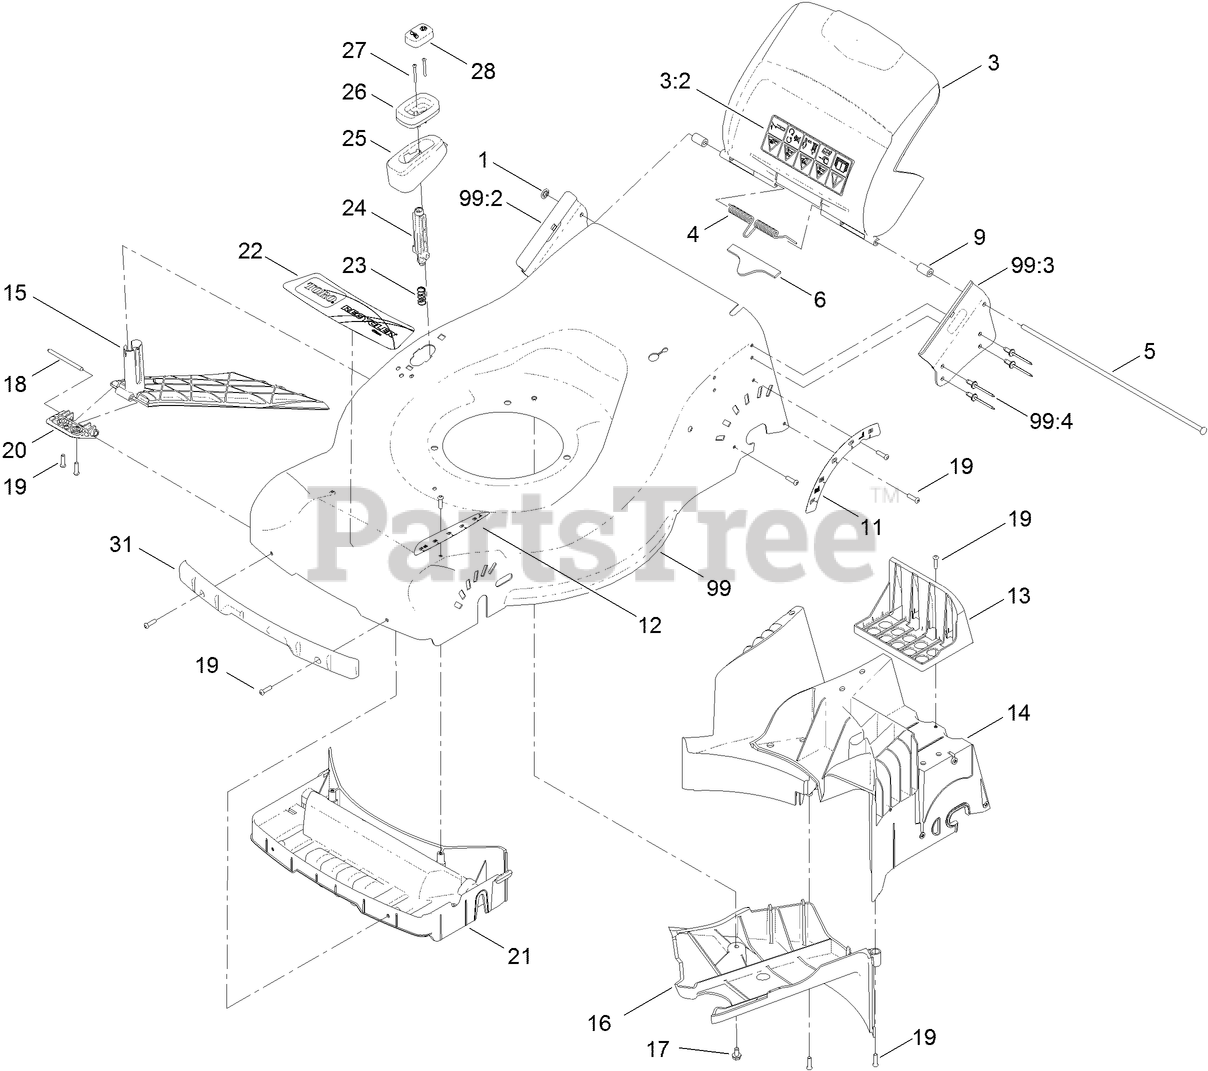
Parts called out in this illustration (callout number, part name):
1	WASHER-STARLOCK, PUSH
3	REAR DOOR ASM
3:2	DECAL-WARNING
4	SPRING-TORSION
5	ROD-PIVOT
6	SEAL-RUBBER
9	SPACER-PLASTIC
11	DECAL-HOC, REAR
13	TRAY-BATTERY
14	BAFFLE-REAR
15	DOOR-RECYCLE
16	COVER-BELT
17	SCREW-HH
18	PIN-HINGE
19	SCREW-TORX, PAN HEAD
20	HINGE-DOOR, RECYCLE
21	BAFFLE-FRONT
22	DECAL-DECK
23	SPRING-COMPRESSION
24	LATCH-RECYCLE
25	COVER-DOOR, RECYCLE
26	HOUSING-KNOB
27	SCREW-TORX, PAN HEAD
28	KNOB-RECYCLE
31	BUMPER-FRONT
99	DECK ASM
99:2	BRACKET-HANDLE, RIGHT
99:3	BRACKET-HANDLE, LEFT
99:4	RIVET-POP
